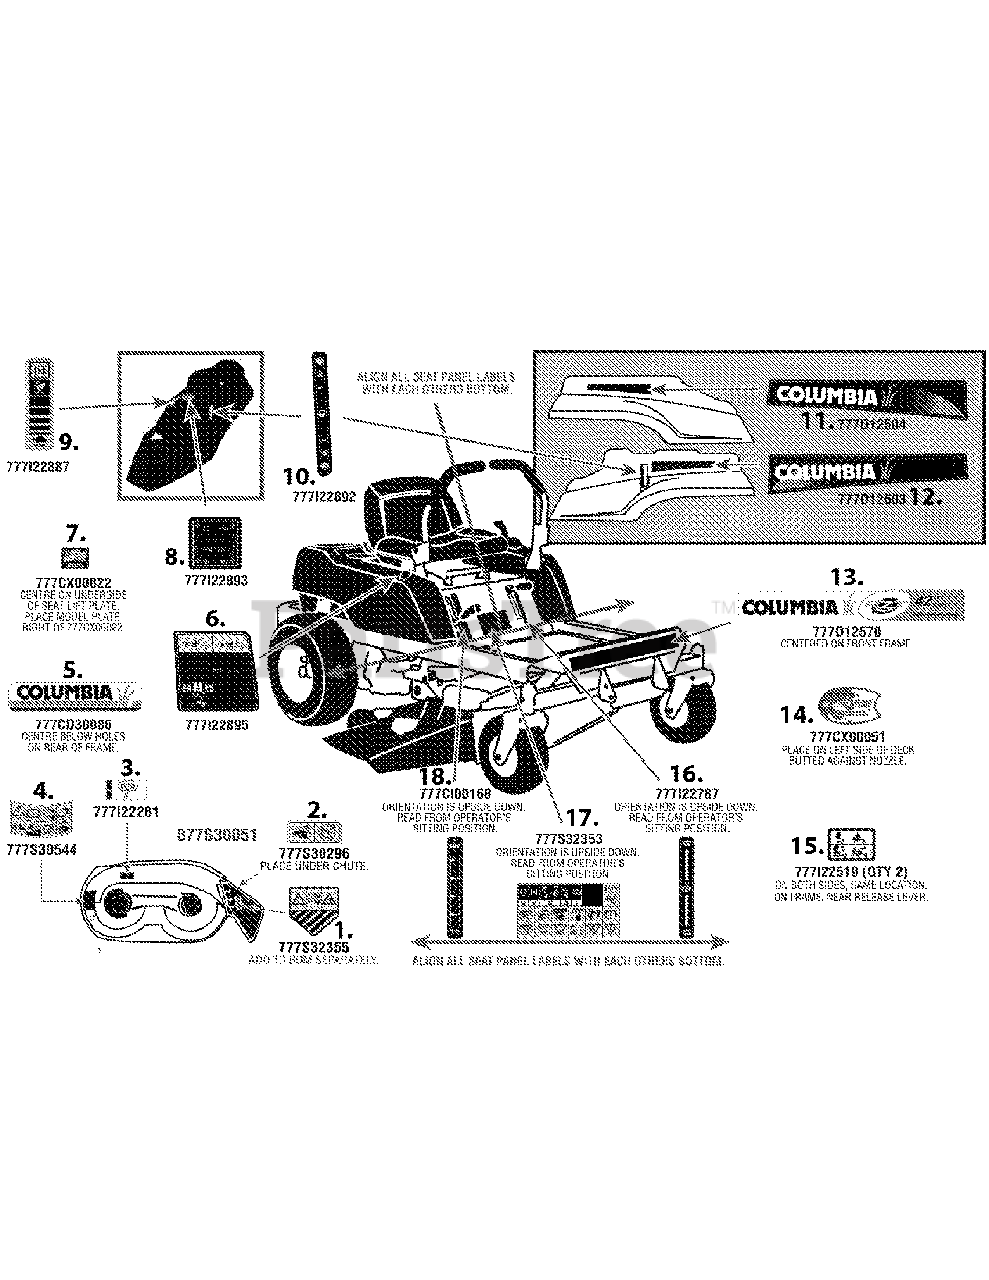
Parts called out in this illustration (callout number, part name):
1	LABEL:RIDER:SAFETY CHUTE DEFL
2	LABEL:RIDER DECK: UNDERCHUTE EXP
3	LABEL-BELT ROUTE
4	LABEL-DECK SAFETY
5	LABEL-REAR FENDER COLUMBIA
6	LABEL-START INSTR RH POD
7	LABEL- MADE IN USA
8	LABEL-HOUR METER LH POD
9	LABEL-THROTT/CHOKE LH POD
10	LABEL-FUEL LEVEL LH POD
11	LABEL-RH POD
12	LABEL-LH POD
13	LABEL-FRNT FRAME 42" COLUMBIA
14	LABEL-DECK WASH
15	LABEL-TRNMSN RELEASE
16	LABEL-PARK BRAKE
17	LABEL-RDR SAFETY
18	LABEL-HANDLE HEIGHT
